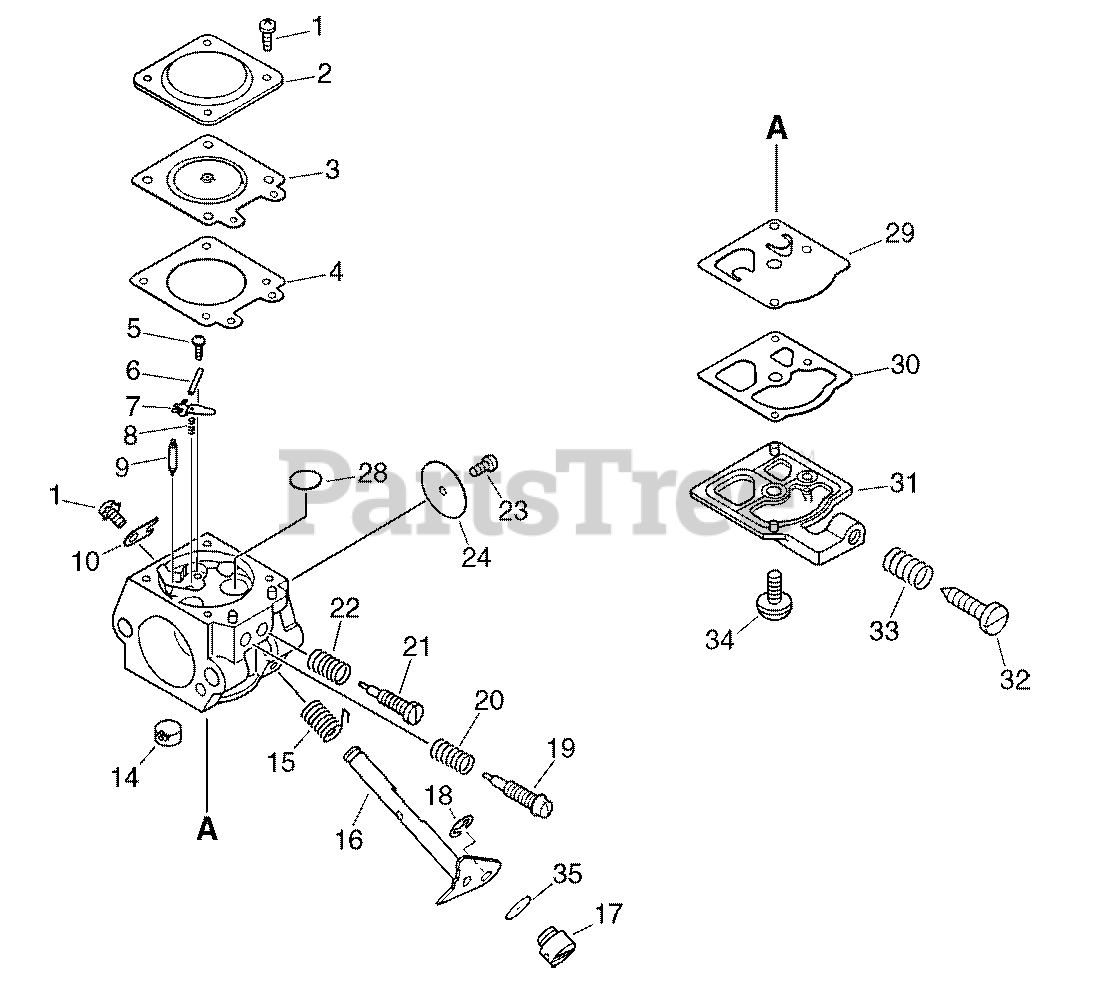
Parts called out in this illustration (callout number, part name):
2	COVER, METERING DIAPHRAGM
3	DIAPHRAGM, METERING
4	GASKET, METERING DIAPHRAGM
5	SCREW, METERING LEVER PIN
6	PIN, METERING LEVER
7	LEVER, METERING
9	VALVE, INLET NEEDLE
10	CLIP, THROTTLE SHAFT
14	SCREEN, FUEL INLET
15	SPRING, THROTTLE
16	SHAFT, THROTTLE
19	NEEDLE, HIGH SPEED
20	SPRING, HIGH NEEDLE
21	NEEDLE, LOW SPEED
22	SPRING, NEEDLE
24	VALVE, THROTTLE
28	PLUG, WELCH
29	DIAPHRAGM, PUMP
30	GASKET, FUEL PUMP
31	COVER, FUEL PUMP
32	SCREW, IDLE ADJUST
